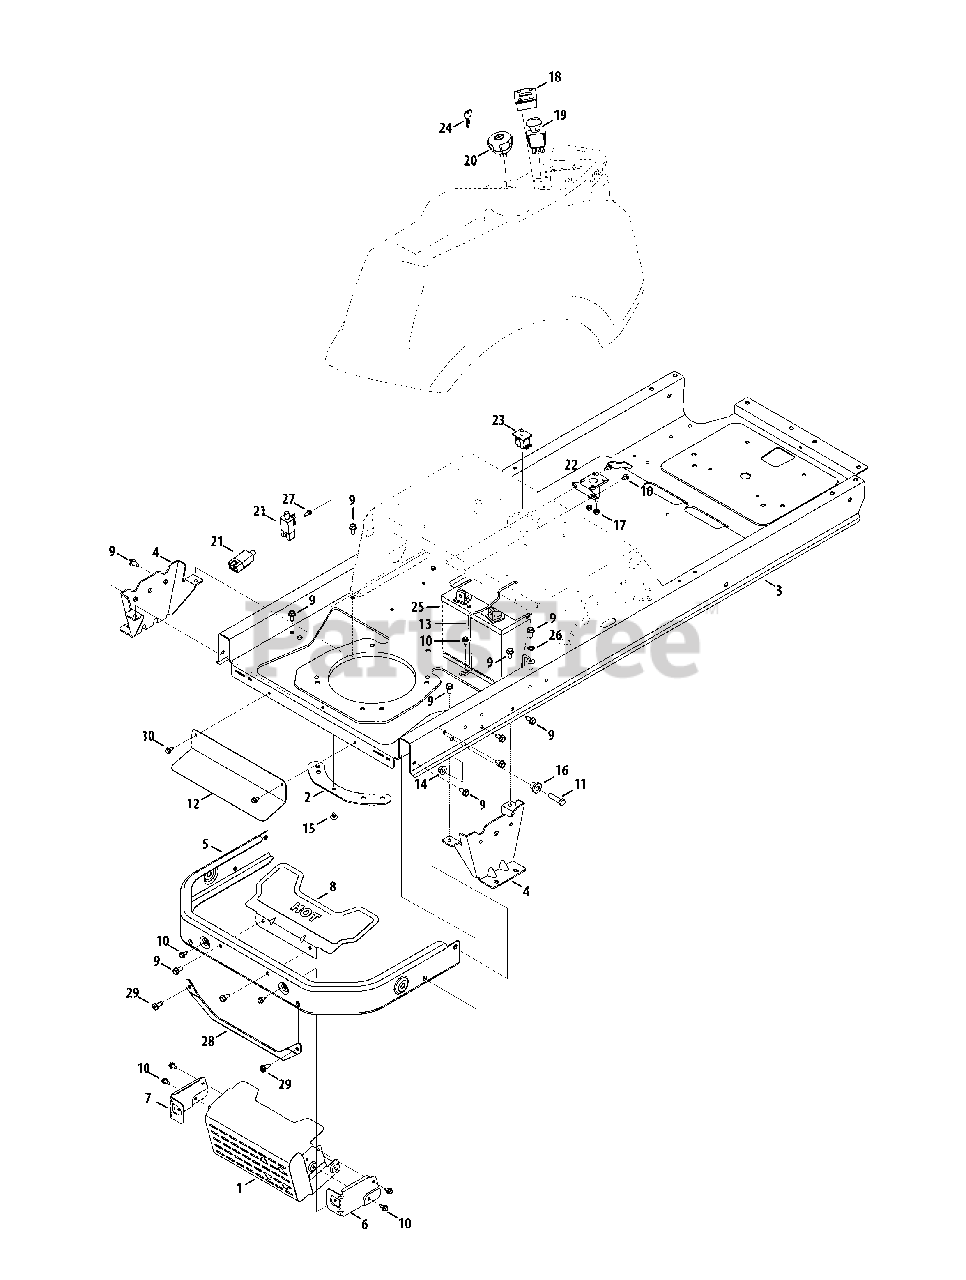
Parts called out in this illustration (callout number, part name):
1	ASSEMBLY, Muffler Shield
2	PLATE, Retainer
3	ASSEMBLY, Frame
4	BRACKET, Transmission Mounting
5	BUMPER, Bumper
6	BRACKET, Muffler Mounting Shield, RH
7	BRACKET, Muffler Mounting Shield, LH
8	SHIELD, Muffler
9	SCREW, 5/16-18 X .750, Hex Washer
10	SCREW, 1/4-20 X .625, Hex Washer
11	SCREW, 3/8-16 X 1.25, Hex
12	SHIELD, Lower Heat
13	ROD, Battery
14	NUT, 3/8-16, Flanged Lock, GR5, Zinc/Clear
15	CLIP, .250 DIA. X .500 LG
16	SPACER, .38 X 1.0 X .70, Shoulder
17	NUT, Nylock Flanged, 1/4-20
18	HOUR METER/SERVICE MINDER
19	SWITCH, Electric PTO
20	SWITCH, Key (Ignition)
21	SWITCH, Interlock
22	SOLENOID
23	SWITCH, Seat
24	ASSEMBLY, Key
25	BATTERY
26	WASHER, 5/16, EXT., Lock
27	SCREW, #10-32 X .500, Shoulder
28	BRACKET, Rear Muffler Shield
29	SCREW, 5/16-18, 0.750, Self-Tapping
